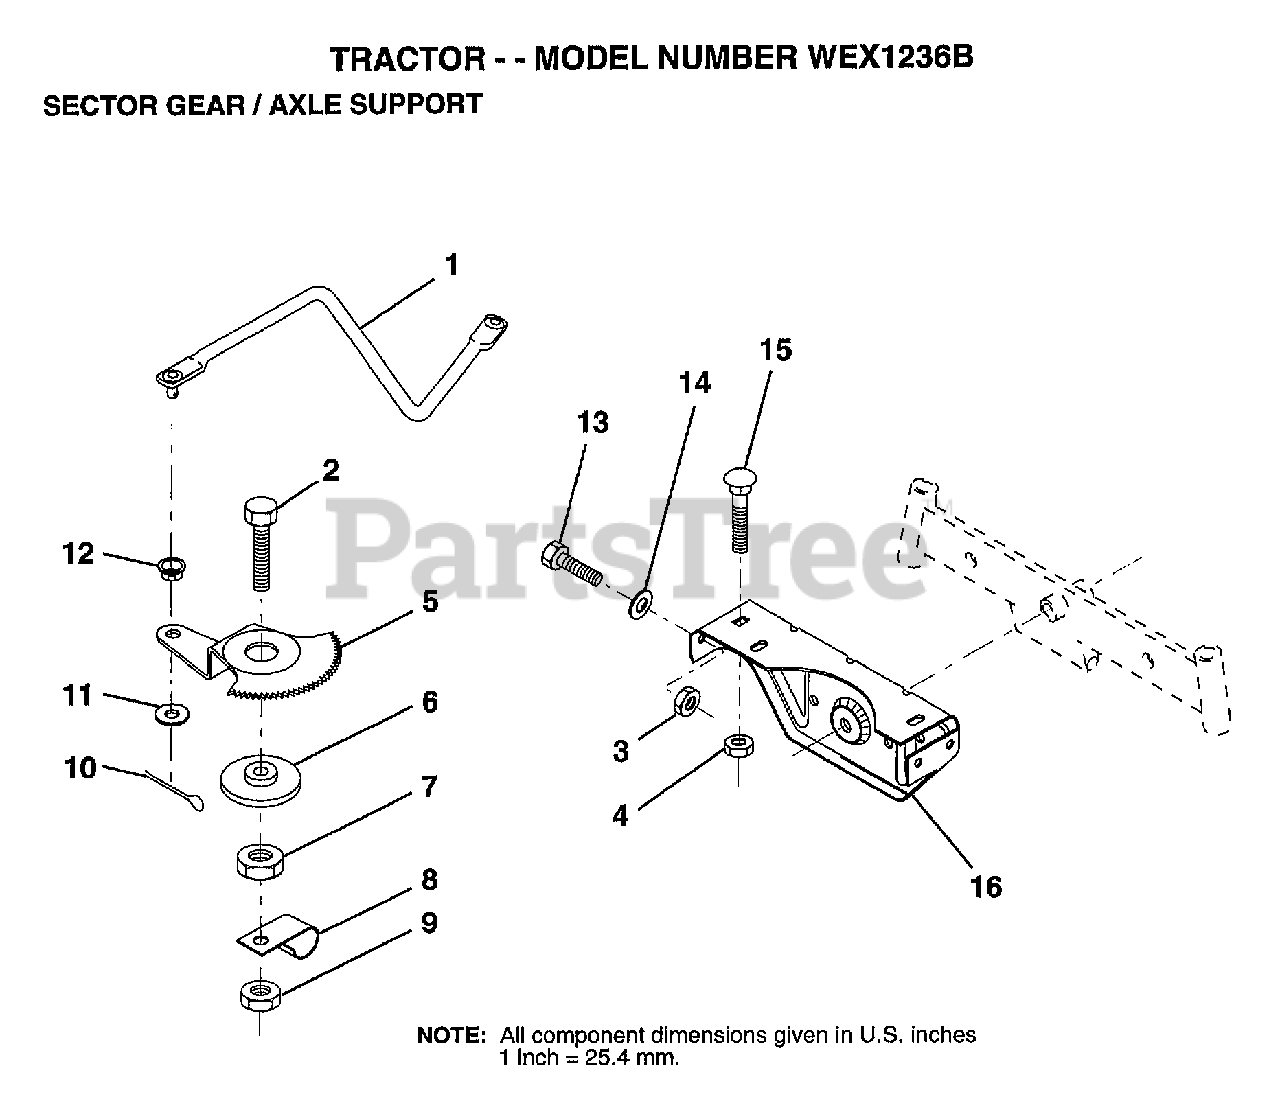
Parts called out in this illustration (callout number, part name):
1	DRAG LINK
2	"BOLT,HEX"
5	GEAR SECTOR
6	BUSHING
7	NUT
8	CLIP INSULATOR
9	NUT LTV
10	COTTER PIN
11	WASHER
12	BUSHING.DRAGLINK
13	BOLT
14	WASHER
15	BOLT
16	SUPT AXLE FRONT
